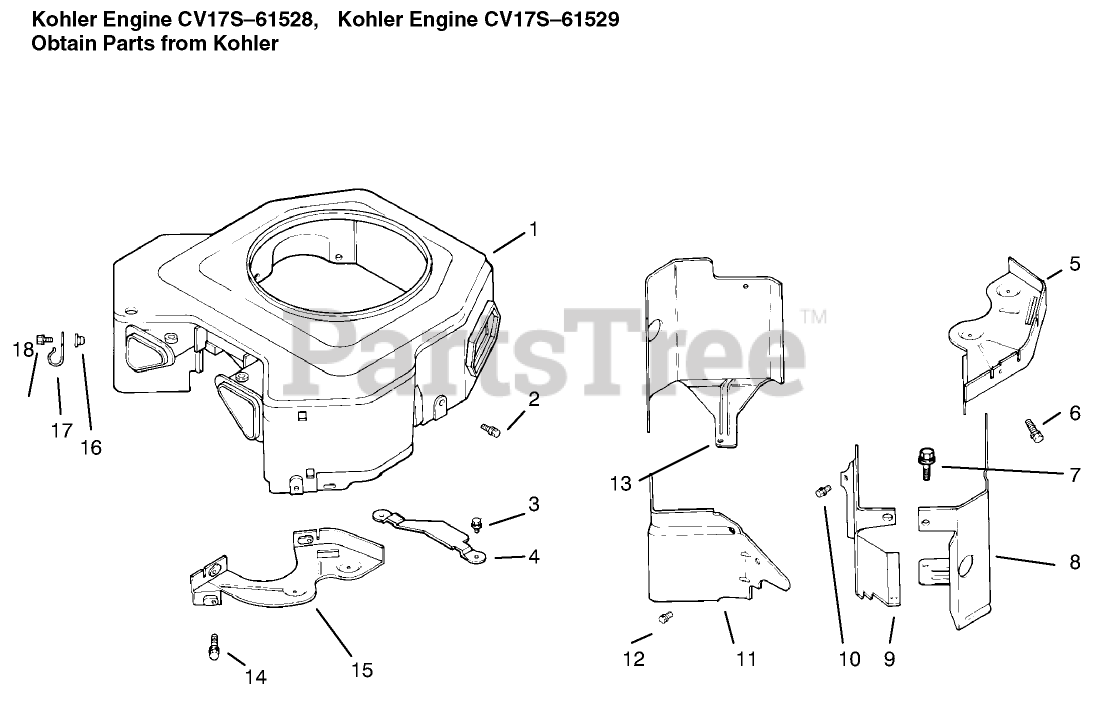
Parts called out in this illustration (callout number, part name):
1	Housing-Blower ASM (Only C)n: 72103, 72083)
4	Guard-Flywheel (Only On: 72103, 72083)
5	Plate-Backing #2 side
8	Baffle Cylinder #2 Side
9	Baffle-Valley #1 Side
11	Baffle-Valley #2 Side (Only On: 72103, 72083)
13	Baffle-Cyl. #1 Side
15	Plate-Backing #1
17	Clip-Cable (Only On: 72103)
